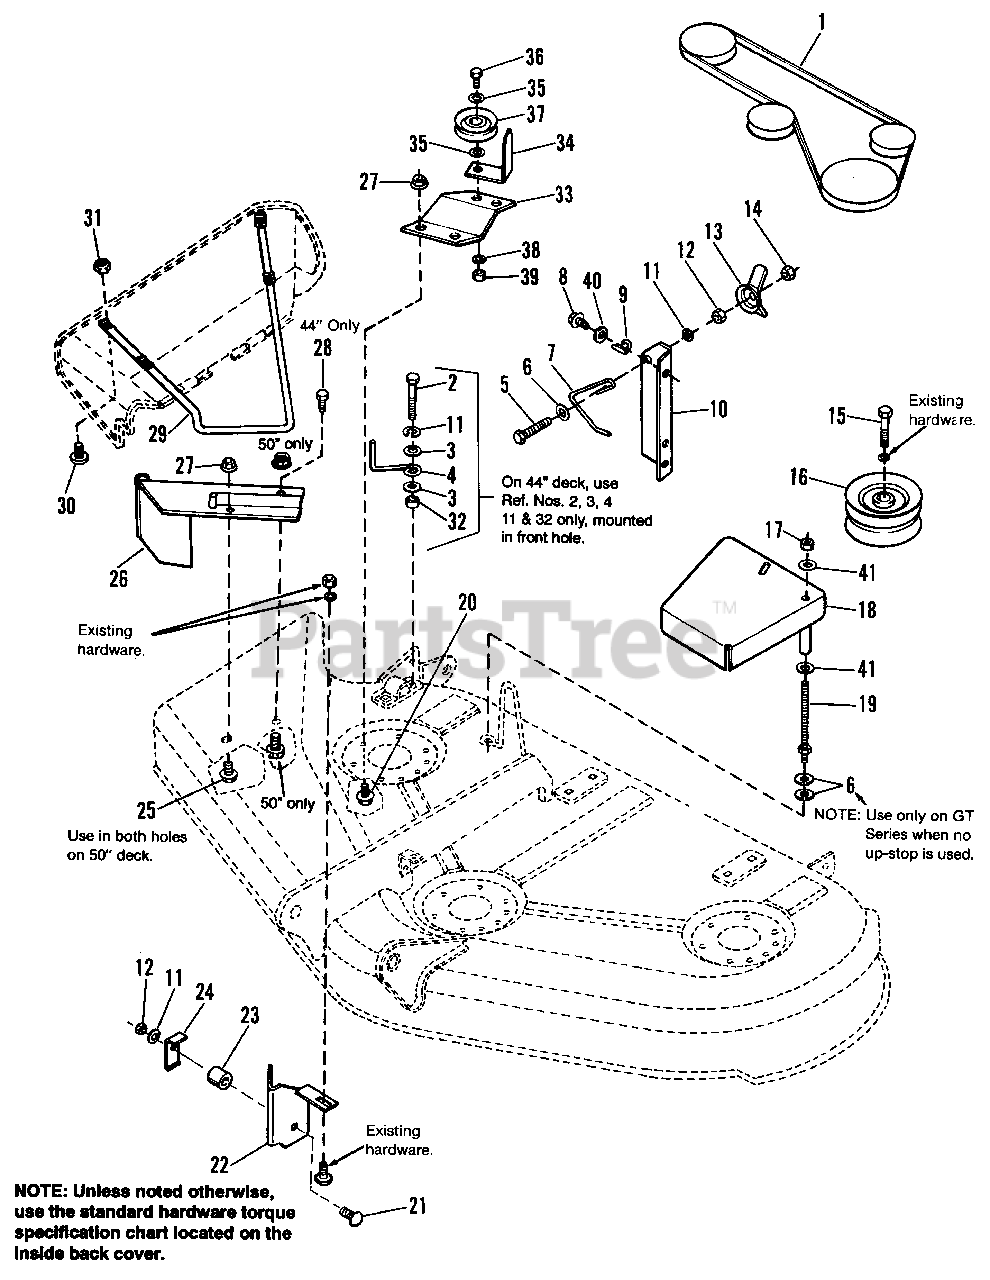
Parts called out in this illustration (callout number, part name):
1	V-BELT (44" Only)
1	V-BELT (50" Only)
2	CAPSCREW, 5/16-18 x 1-1/2 (44" Only)
3	WASHER, Flat (44" Only)
5	CAPSCREW, Hex Hd., 5/16-18 x 2-1/2
6	WASHER, Flat
7	SPRING LATCH
8	SCREW, Taptite, 1/4-20 x 1/2
10	ANCHOR, Turbo
11	LOCKWASHER, 5/16 (Qty. 3 used on 44")
12	NUT, Hex, 5/16-18
13	NUT, Wing Assy., 5/16
14	NUT, Hex, Center Lock, 5/16-18
15	CAPSCREW, Hex Hd., 7/16-14 x 2
16	PULLEY ASSY., Turbo
17	NUT, Hex, Ny-lock
18	SHIELD ASSY., Belt
19	STUD, 5/16-18 x 5-13/64
20	CAPSCREW, Hex Hd., 5/16-18 x 7/8
21	CARRIAGE BOLT, 5/16-18 x 1-1/4
22	BRACKET ASSY., Cut off
24	BRACKET, "L"
25	CARRIAGE BOLT, 5/16-18 x 3/4 (Qty. 2 used on 44")
26	PIVOT ASSY., (44" Only)
26	PIVOT ASSY., (50" Only)
27	NUT, Hex, Flange, Whizlock, 5/16-18 (Qty. 3 used on 44")
28	SCREW, Hex, Whizlock, 5/16-18 x 1/2 (44" Only)
29	ROD, Deflector
30	SCREW, Truss Hd.
31	NUT, Nylock, #10-24
32	SPACER (44" Only)
33	BRACKET, Idler, Turbo
34	LATCH, Belt Cover
35	WASHER, Flat
36	CAPSCREW, 3/8-16 x 1-1/2
37	PULLEY ASSY., Idler
38	LOCKWASHER, 3/8
39	NUT, Hex, 3/8-16
40	WASHER, Flat, .25 x .05 Thk.
41	WASHER, Flat
